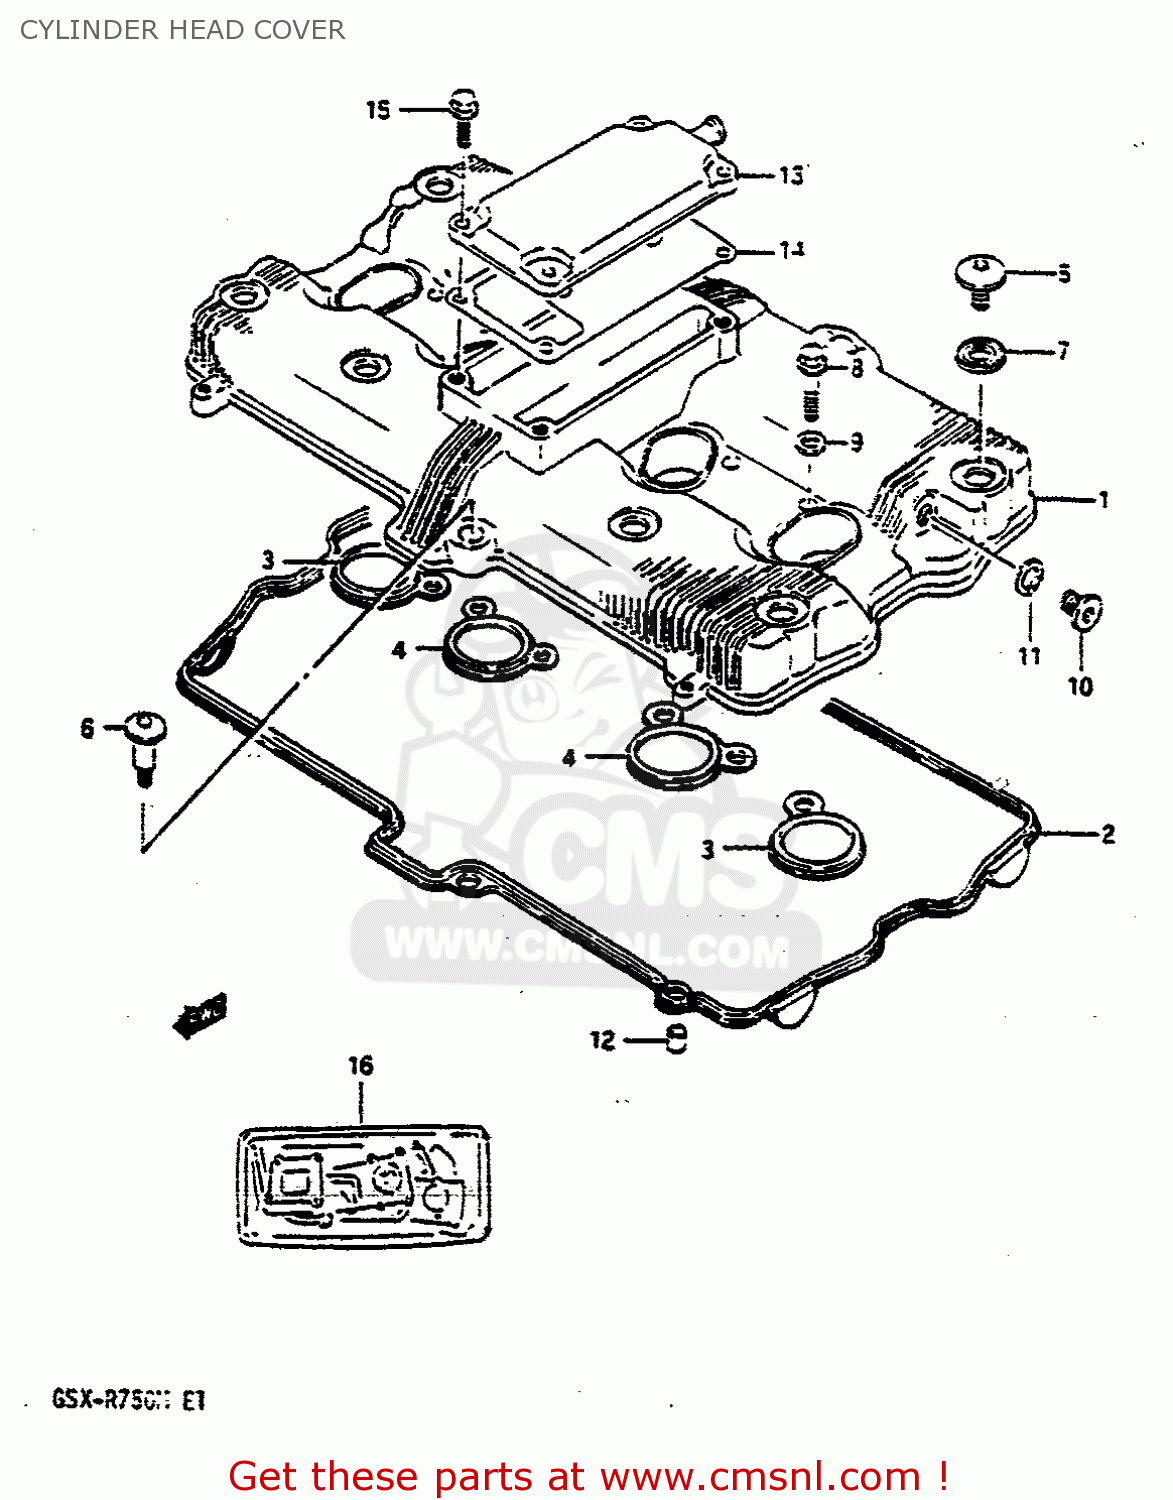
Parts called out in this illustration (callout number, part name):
1	COVER,CYLINDER HEAD
2	GASKET,CYLINDER HEAD COVER (NAS)
3	GASKET,HEAD COVER NO.2 (NAS)
4	GASKET,HEAD COVER NO.3 (NAS)
5	BOLT(7X17.5)
6	BOLT(7X31)
7	WASHER(10.6X25.5X2.3)
8	BOLT,UNION 8X35
9	GASKET 8.2X14X1 (NAS)
10	PLUG(L:12)
11	GASKET(12.1X16.2X3.7) (NAS)
12	PIN
13	COVER,BREATHER
14	GASKET,BREATHER COVER (NAS)
15	BOLT 6X20
16	GASKET SET (NAS)
